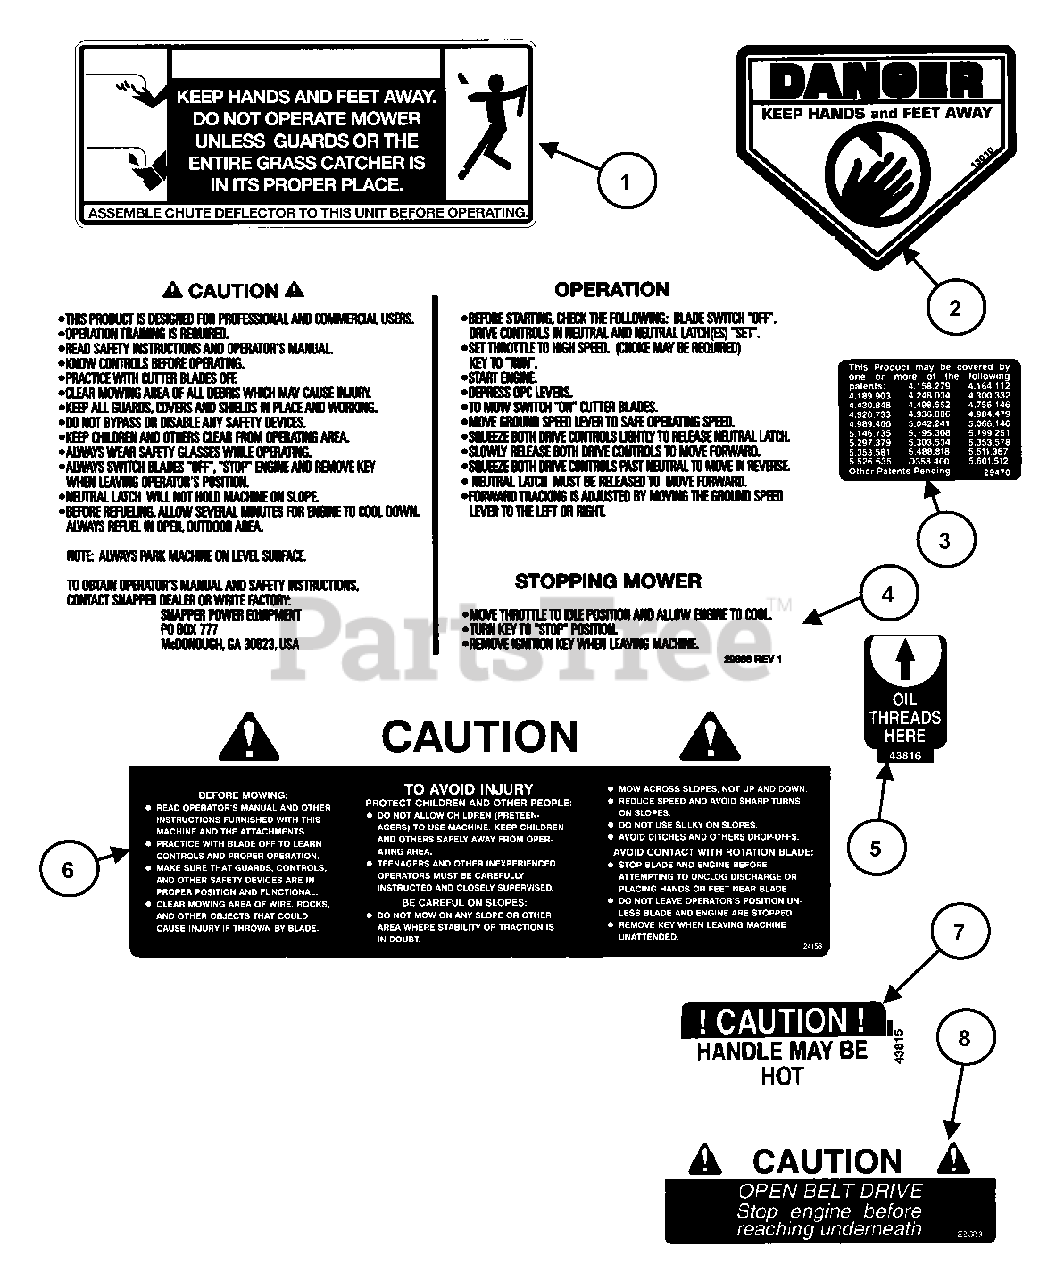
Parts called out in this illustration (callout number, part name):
1	DECAL, Warning
2	DECAL, Warning
3	DECAL, Patent Numbers
4	DECAL, Caution Pro Hydro
5	DECAL, Oil
6	DECAL, Caution
7	DECAL, Caution
8	DECAL, Caution
